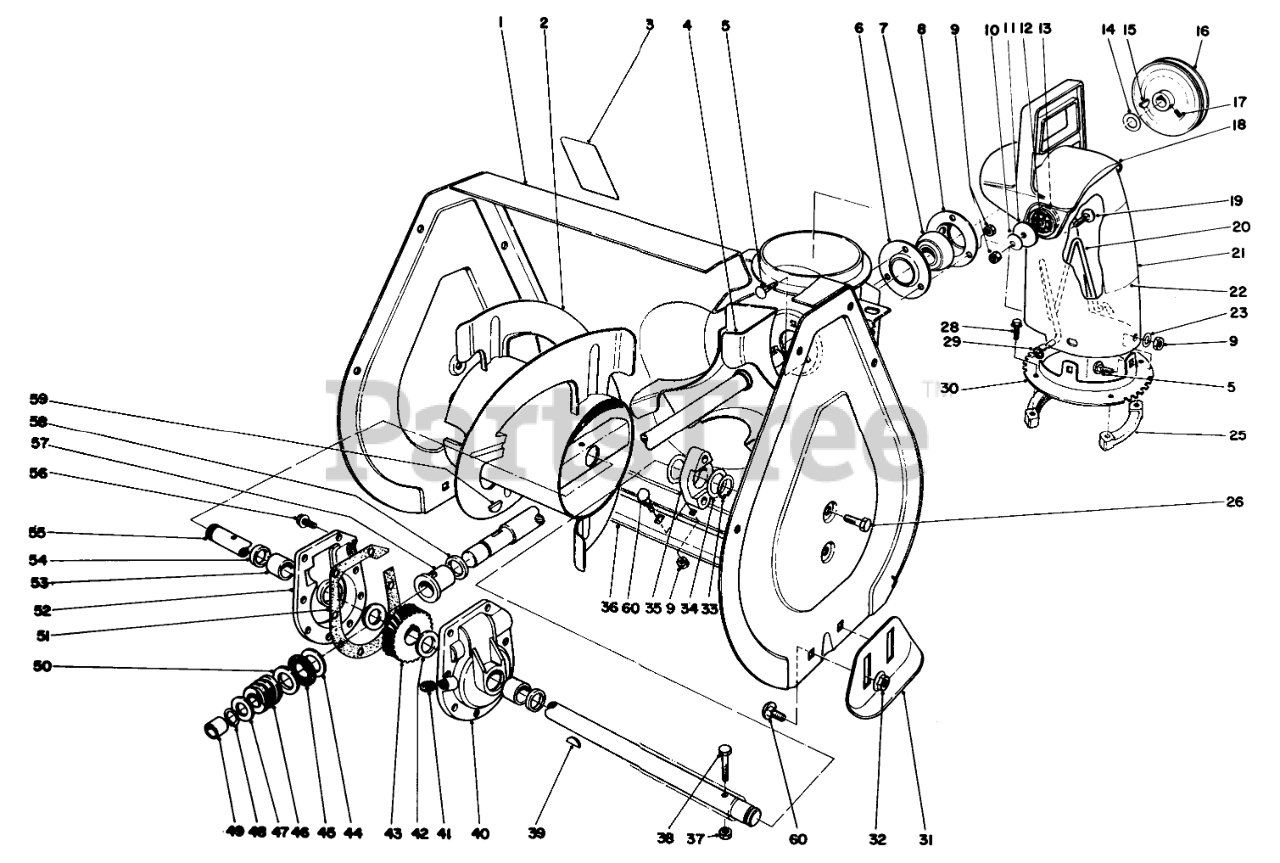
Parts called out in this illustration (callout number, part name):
1	Housing-Auger (Incl. Ref. #3 & 27)
2	Auger R.H.
3	DECAL-WARNING, AUGER
4	Shaft & Impeiler
5	SCREW-CARR
6	FLANGE-CUP, BEARING
7	Ball Bearing
8	FLANGE-CUP, BEARING
9	NUT-LOCK, NI
10	WASHER-BELLEVILLE
11	WASHER-FLAT
12	PLATE-FRICTION
13	WASHER-RUBBER
14	WASHER
15	KEY-WOODRUFF
16	PULLEY
17	SCREW-SET, SQH
18	CHUTE-DEFLECTOR
19	SCREW-CARR
20	WIRE-CHUTE
21	Chute Discharge (Incl. Ref. #22) (Model 38052)
21	Chute Discharge (Incl. Ref. #22) (Model 38052C)
22	Decal-Danger
22	DECAL-DANGER DISCH.
23	WASHER-PLAIN
25	RING-CHUTE, RETAINER
26	SCREW-HWHTF
28	SCREW-SPECIAL
29	NUT-PUSH
30	Chute Ring
31	Skid
32	NUT-HF
33	RING-RETAINING
34	WASHER
35	BEARING-AUGER
36	Blade-Scraper
37	NUT-LOCK, CONE
38	SCREW-HH
39	KEY-WOODRUFF
40	Gear Case-L.H. (Incl. Ref. #53 & 54)
41	PLUG-PIPE, SQH
42	WASHER-THRUST
43	Gear
44	WASHER-THRUST
45	BEARING-THRUST
47	WASHER-THRUST
48	Ring-Snap
49	BUSHING
50	WASHER-THRUST
51	GASKET-CASE, GEAR
52	Gear Case-R.H. (Incl. Ref. #53 & 54)
53	BUSHING
54	SEAL-OIL
55	AUGER SHAFT
56	SCREW-TAPTITE
57	BUSHING-INPUT
58	RING-QUAD
59	KEY-WOODRUFF
60	BOLT-CARR
